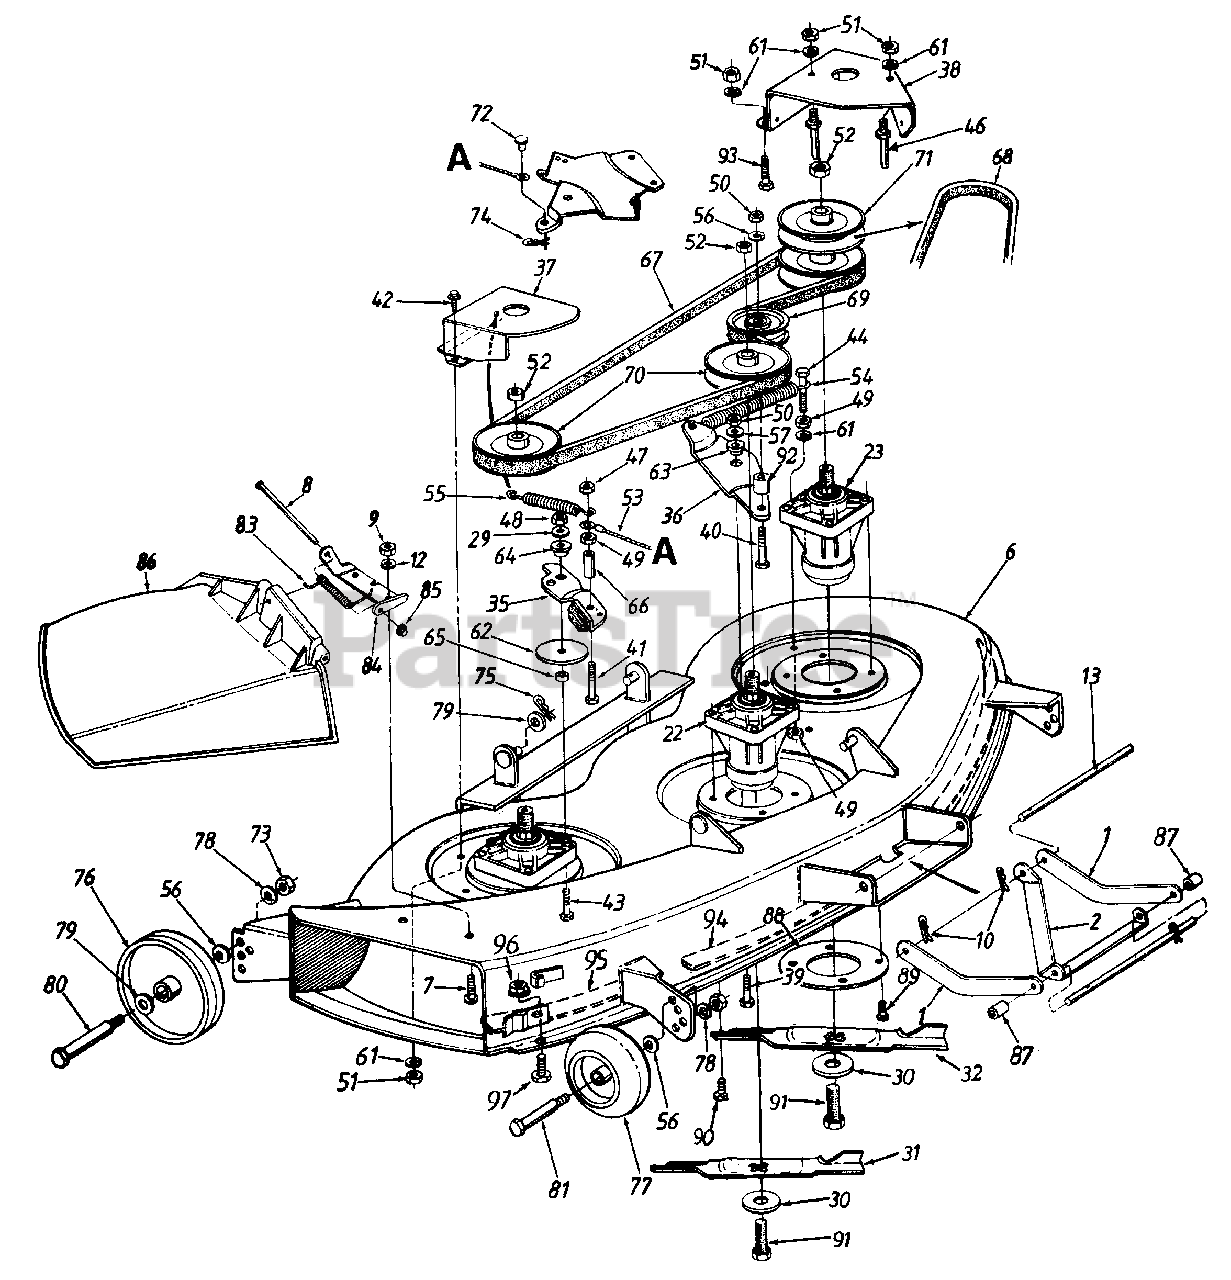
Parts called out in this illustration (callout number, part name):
8	Hinge Pin
9	Hex Nut 1/4-20 Thd.
10	Hairpin Clip
12	Bell-Wash. 1/4" I.D.
13	Deck Connecting Rod
22	Spindle Ass'y. (R.H. & Center)
23	Spindle Ass'y. (L.H.)
29	Lock Wash. 5/16" I.D.
30	Bell-Wash. .47" I.D. x 1.5"
31	High Lift Blade 14.88" Lg. (Middle)
32	High LIft Blade 16.28" Lg. (R.H. & L.H.)
35	Deck Brake Brkt. Ass'y.
36	Idler Bracket
39	Hex Bolt 3/8-24 x 1.0" Lg.
40	Hex Bolt 3/8-24 x 2" Lg.
41	Hex Bolt 1/4-28 x 1.75" Lg.
42	Hex Wash. Hd. Tap-Scr. 1/4-20 x .5" Lg.
43	Hex Bolt 5/16-24 x 1.5" Lg. (Grade 5)
44	Hex Bolt 1/4-28 x 1.5" Lg.
46	Belt Guard PIn 1/4" Dia.
47	Hex Cent. L-Nut 1/4-28 Thd.
48	Hex Nut 5/16-24 Thd.
49	Hex Nut 1/4-28 Thd.
50	Hex Nut 3/8-24 Thd.
51	Hex Nut 1/4-20 Thd.
52	Hex Flange L-Nut 5/16-18 Thd.
53	Brake Cable Ass'y.
54	Extension Spring 6.17" Lg.
55	Extension Spring 3.97" Lg.
56	Bell-Wash. .38" I.D. x .88" O.D.
57	Bell-Wash. .39" I.D. x 1.13" O.D.
61	L-Wash. 1/4" I.D.
62	Fl-Wash. 5/16" I.D. x 3" O.D.
63	Shld. Spacer .625" I.D.
64	Shld. Spacer
65	Spacer .34" I.D.
66	Spacer .326" I.D.
67	V-Belt
68	V-Belt
69	Fl-Idler Pulley 3.5" O.D.
70	Pulley 5.0" Dia.
71	Double Pulley 5.0" Dia.
72	Clevis Pin 1/4" Dia. x .53" Lg.
73	Hex Nut 3/8-16 Thd.
74	Intern. Cotter Pin 5/16" Dia.
75	Intern. Cotter Pin 3/8 Dia.
76	Deck Wheel 5" Dia.
77	Deck Wheel w/Insert 5" Dia.
78	L-Wash. 3/8" I.D.
79	Fl-Wash. .531" I.D.
80	Shoulder Bolt .498" Dia. x 1.64" Lg.
81	Shoulder Bolt
83	Torsion Spring
84	Hinge Mtg. Brkt.
85	Push Nut
86	Chute Ass'y. Comp.
87	Spacer 5/8" I.D. x 7/8" O.D.
90	Hex Wash. Hd. Scr. 5/16-18 x .75" Lg.
91	Hex L-Bolt 7/16-20 x 1" Lg.
92	Spacer .38" I.D.
93	Hex Bolt 1/4-20 x .5" Lg.
96	Hex Sems Nut 1/4-20 Thd.
97	Carriage Bolt 1/4-20 x .5" Lg.
